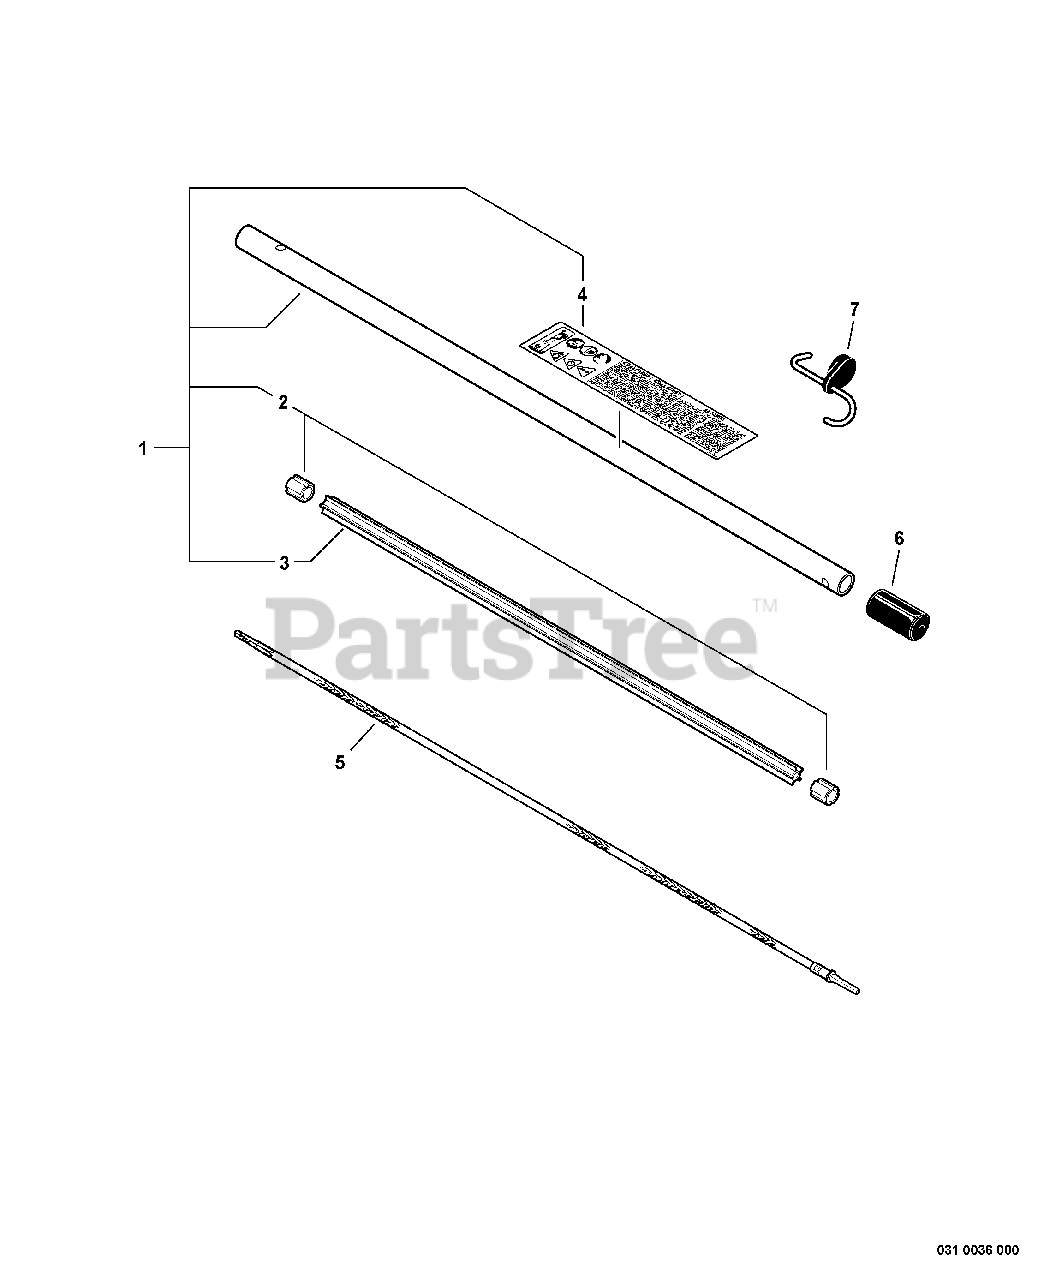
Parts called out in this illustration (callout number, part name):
1	MAIN PIPE ASSY
3	LINER - FLEXIBLE
4	LABEL, CAUTION
5	DRIVESHAFT - FLEXIBLE
6	CAP, MAIN PIPE
7	HANGER, ATTACHMENT
